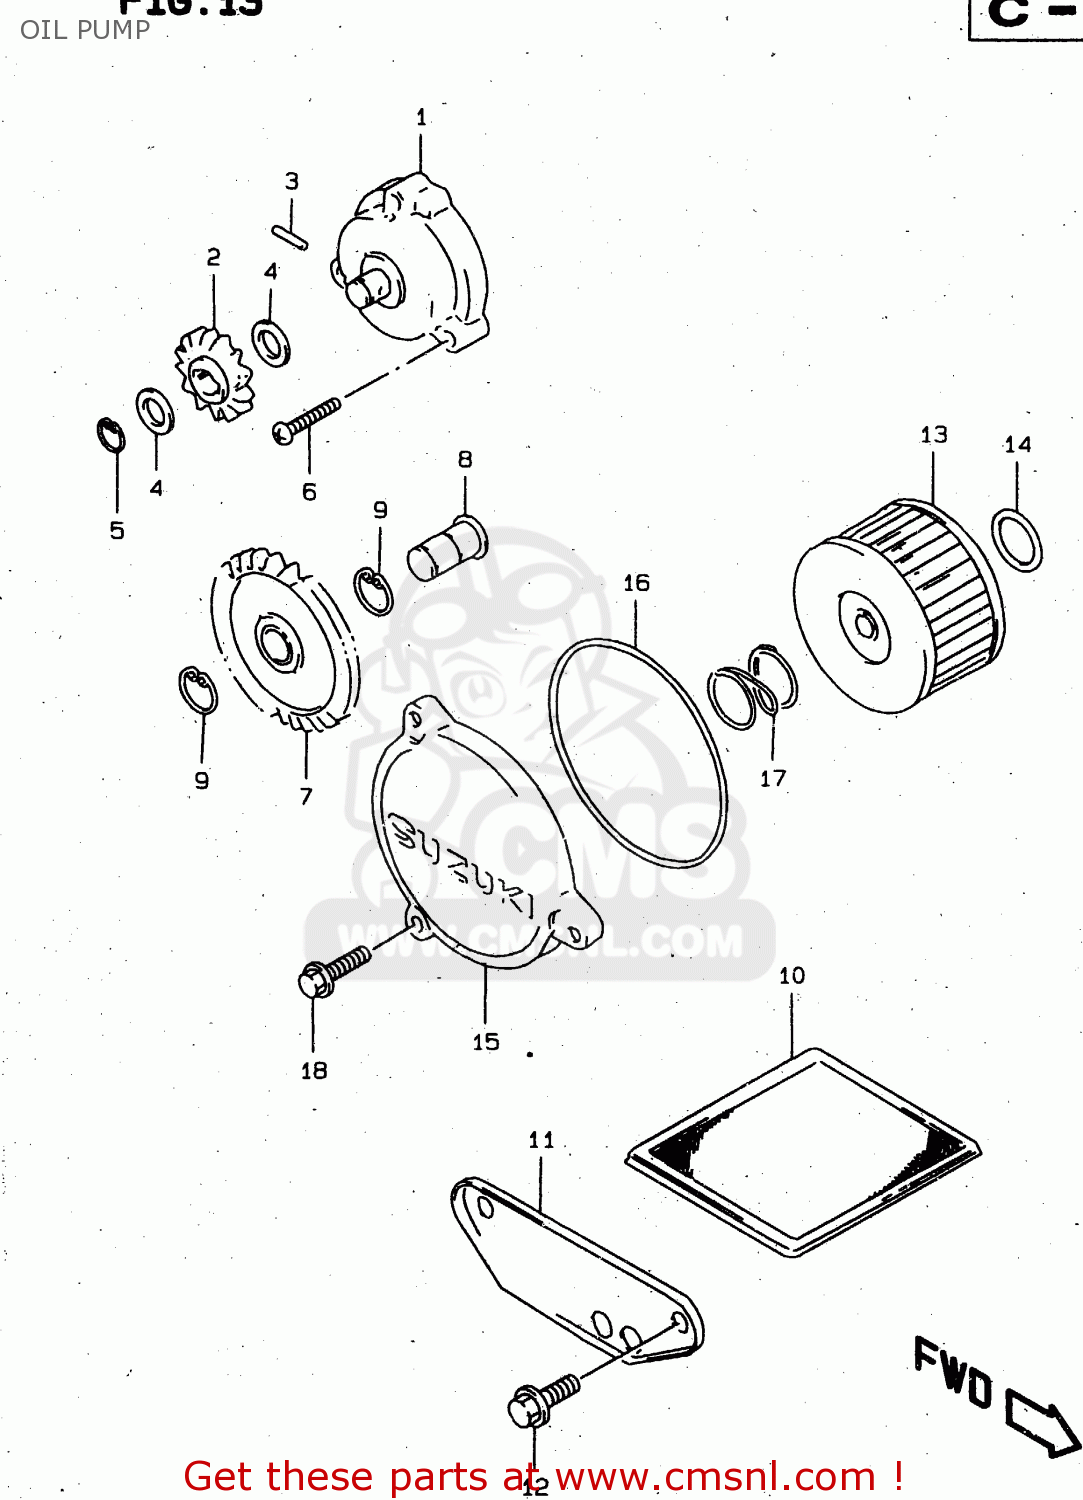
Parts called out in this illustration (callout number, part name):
1	PUMP ASSY,ENGINE OIL
2	GEAR,ENG OIL PUMP DRIVEN
3	PIN(4X15.8)
4	SHIM
5	CIRCLIP,10MM
6	SCREW
7	GEAR,OIL PUMP DRIVE(NT:30)
8	SHAFT,ENGINE OIL PUMP DRIVE
9	CIRCLIP,12 MM
10	STRAINER,ENGINE OIL
11	CAP,OIL STRAINER
12	BOLT 6X12
13	FILTER ASSY,ENGINE OIL
14	O RING(D:2.4,ID:15.8)
15	CAP,OIL FILTER
16	O RING(D:2.4,ID:73)
17	SPRING
18	BOLT
